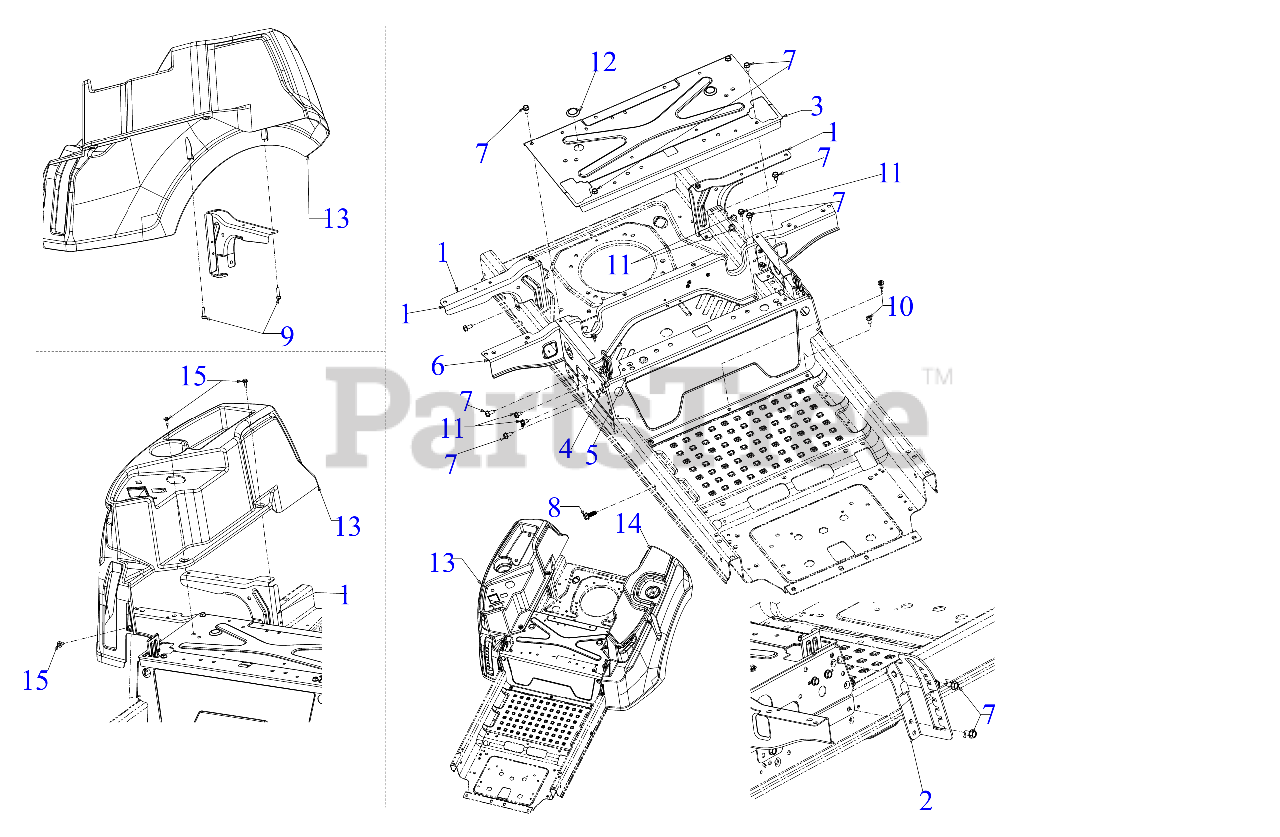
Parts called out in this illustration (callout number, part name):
2	HEIGHT INDEX BRACKET
7	SCREW 5/16-18 x .750
8	SCREW 3/8-16 x 1
9	SCREW 5/16-14 x 1
10	SCREW 5/16-18 x .500
11	SCREW 5/16-18 X.75
13	CONSOLE (RH) (W/O RMC)
14	CONSOLE (LH)
15	SHOULDER SCREW M6-1 .368 X.115
